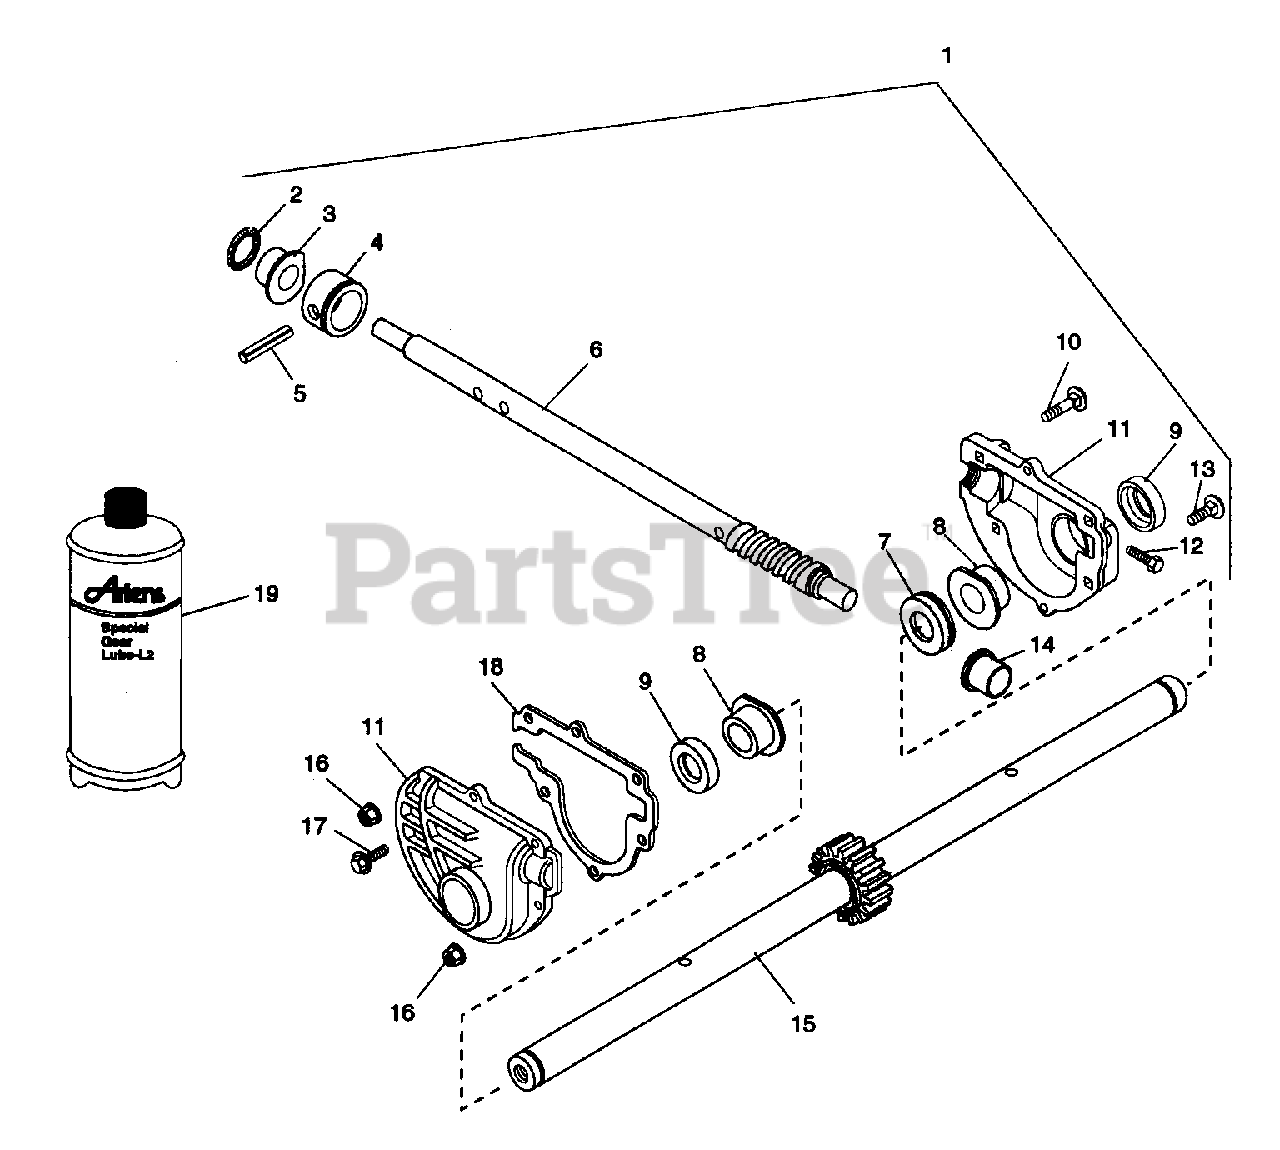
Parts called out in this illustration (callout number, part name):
1	GEAR CASE ASSEMBLY
2	SEAL .750X1.00X.156
3	BSHG-FLG .750X1.000X.750X1.250
4	THRUST COLLAR
5	PIN-GRV .188X1.25 TP A
6	WORM SHAFT & GEAR ASSY
7	THRUST COLLAR-AUGER SHAFT
8	BSHG-FLG 1.003X1.5X.625
9	SEAL 1.000X1.312X.150
10	BLT-RDHDSQNK .25-20X1.25 GR5PL
11	L. H. GEAR CASE HALF
11	R. H. GEAR CASE HALF
12	SCR-TAP .375-16X .50 HWH PL TR
13	BLT-RDHDSQNK .25-20X1.00 GR5
14	BSHG-FLG .502X1X.750
15	AUGER SHAFT WELD ASSY
16	NUT-LK-FLG .250-20 PL
17	SCR-TAP 10-24X.75 HWH PL TR
18	GASKET
19	BOTTLE ONLY-S.SCREEN.FOR NO.80
